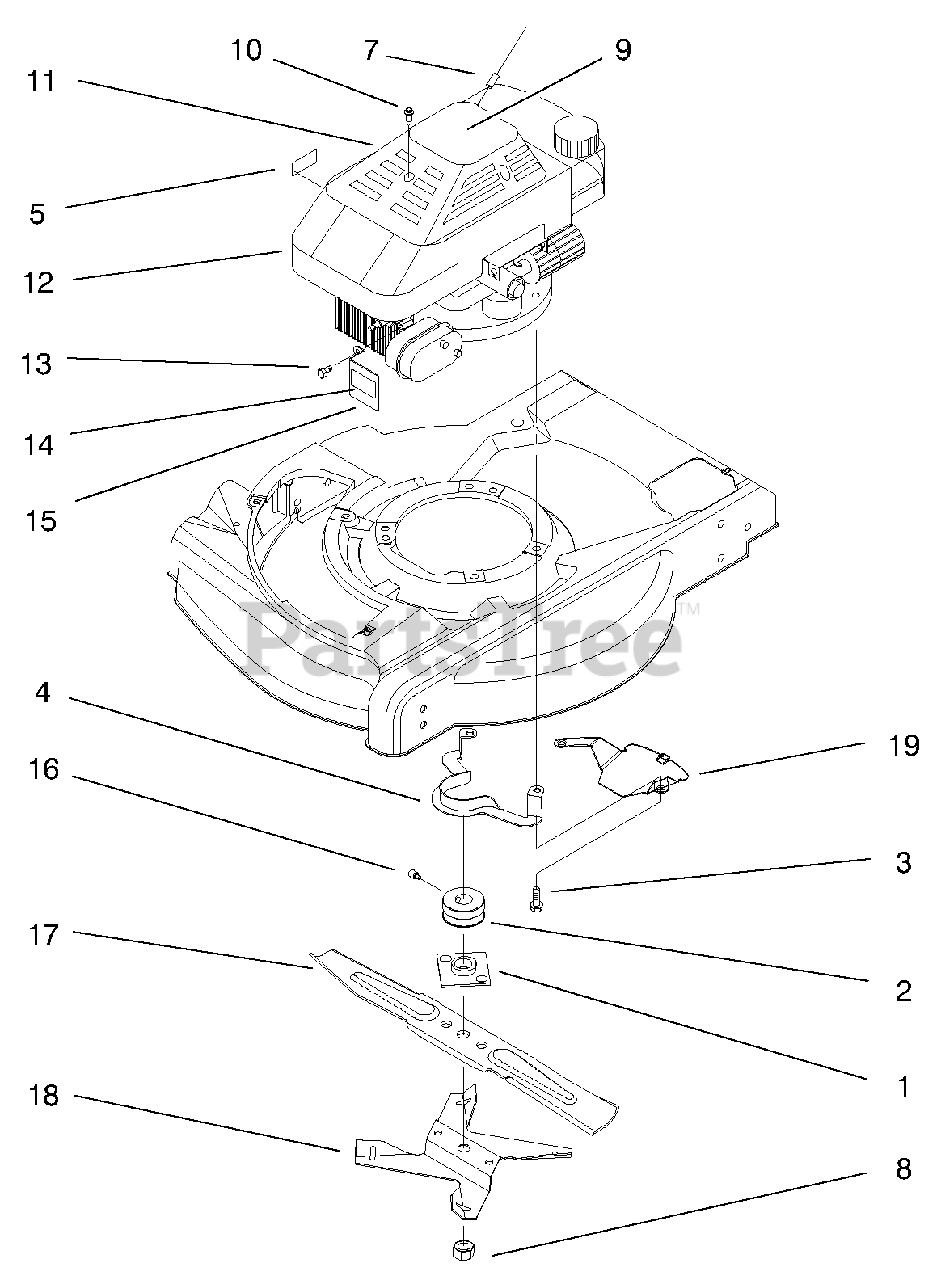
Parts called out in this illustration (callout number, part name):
1	Plate & Collar ASM
3	Screw-Taptite w/Patch
4	Belt Guide
5	Decal-Oil Instr.
7	Rope-Stop
8	Nut-Blade
9	Decal-Recoil
10	Screw-Recoil Cover
11	Cover-Starter
12	Shroud-Engine
13	Screw-TAP
14	Decal-Hot Surface
14	ASM-Muffler Guard
15	Guard-Muffler
16	Screw-Set
17	Blade-21" Whirl
18	Fan-Mulching
19	Shield-Grass
